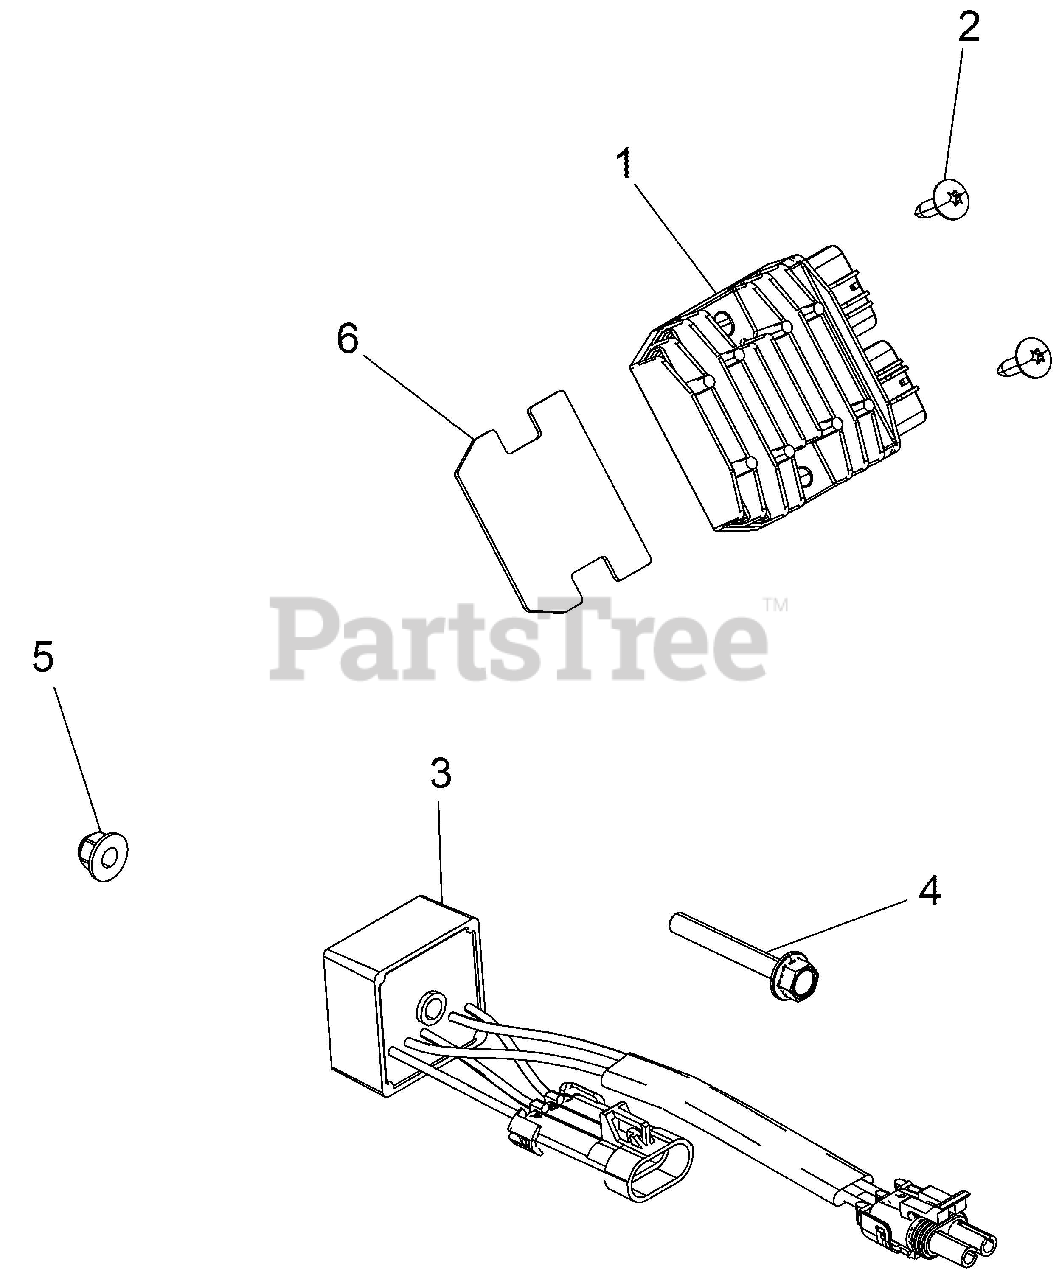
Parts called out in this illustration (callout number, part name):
1	REGULATOR-3PH,50A,SERIES,HISPD
2	SCR-TFHFL-M6X1.0X25,ZOD
3	RELAY, SOLID STATE,9A,LONG LD
4	BOLT-M6X1.0X35,HXFLG/SH-OLV D
5	NUT-M6X1.0,FLG-NYLOC-OLIVE D
6	COVER-VOLTAGE REGULATOR
